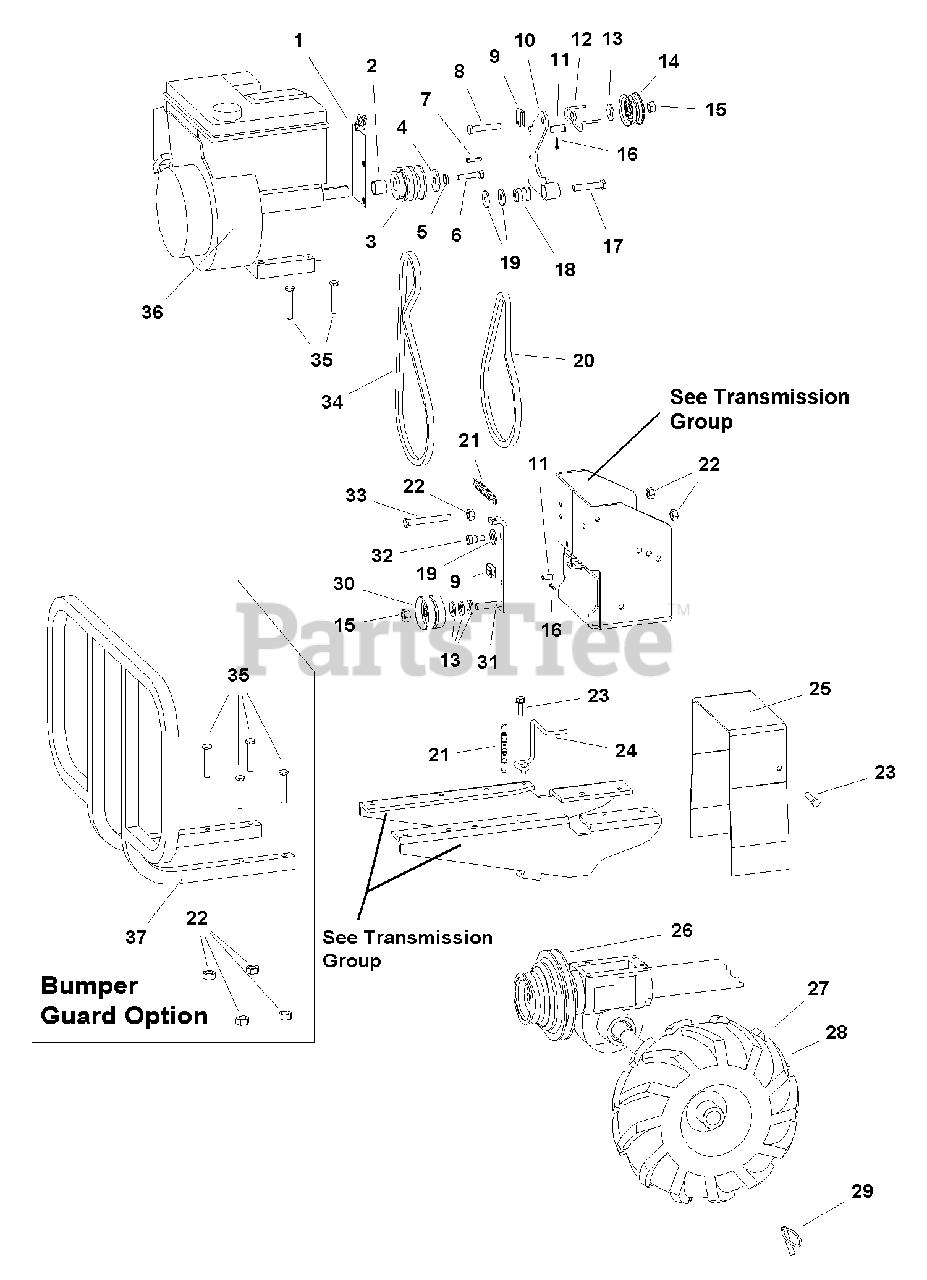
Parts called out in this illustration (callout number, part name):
1	BRACKET, Engine
2	SPACER, Engine
3	PULLEY, Engine 2 Groove
5	LOCKWASHER, Spring 5/16"
6	CAPSCREW, Hex Head 5/16" - 24 x 3/4" G5
7	KEY, PARALLEL PLN 3/16" x 3/16 x 1-3/32"
8	CAPSCREW, Hex Head 3/8" - 24 x 2" G5
9	YOKE, Cable
11	PIN, Link Forward/Reverse
12	GUIDE, Belt Reverse
13	WASHER, 3/8"
14	PULLEY, Idler Reverse
15	NUT, Hex 3/8" - 16NC, 2B
16	PIN, Cotter
17	BOLT, Hex Head 5/16" - 24 x 1-1/2"
19	WASHER, 5/16"
20	V-BELT, Forward
21	SPRING, Idler Arm
22	NUT, Hex Flange 5/16" - 18 Two, Way Lock GA
23	BOLT, Hex Flange Head 5/16" - 18 x 3/4"
24	GUIDE, Belt Forward
25	COVER, Belt
26	PULLEY, Transmission 2 Groove
27	Wheel & TIRE ASSEMBLY TILLER, Left
28	Wheel & TIRE ASSEMBLY TILLER, Right
30	PULLEY, Forward Idler
31	ARM, Idler Forward
32	SCREW, Hex Socket Shoulder 5/16" - 18 x 3/8"
33	CAPSCREW, Hex Head 5/16" - 18 x 3-1/2" G5
34	V-BELT, Reverse
35	CAPSCREW, Hex Head 5/16" - 18 x 1-3/4" G5
37	** BUMPER, Guard
